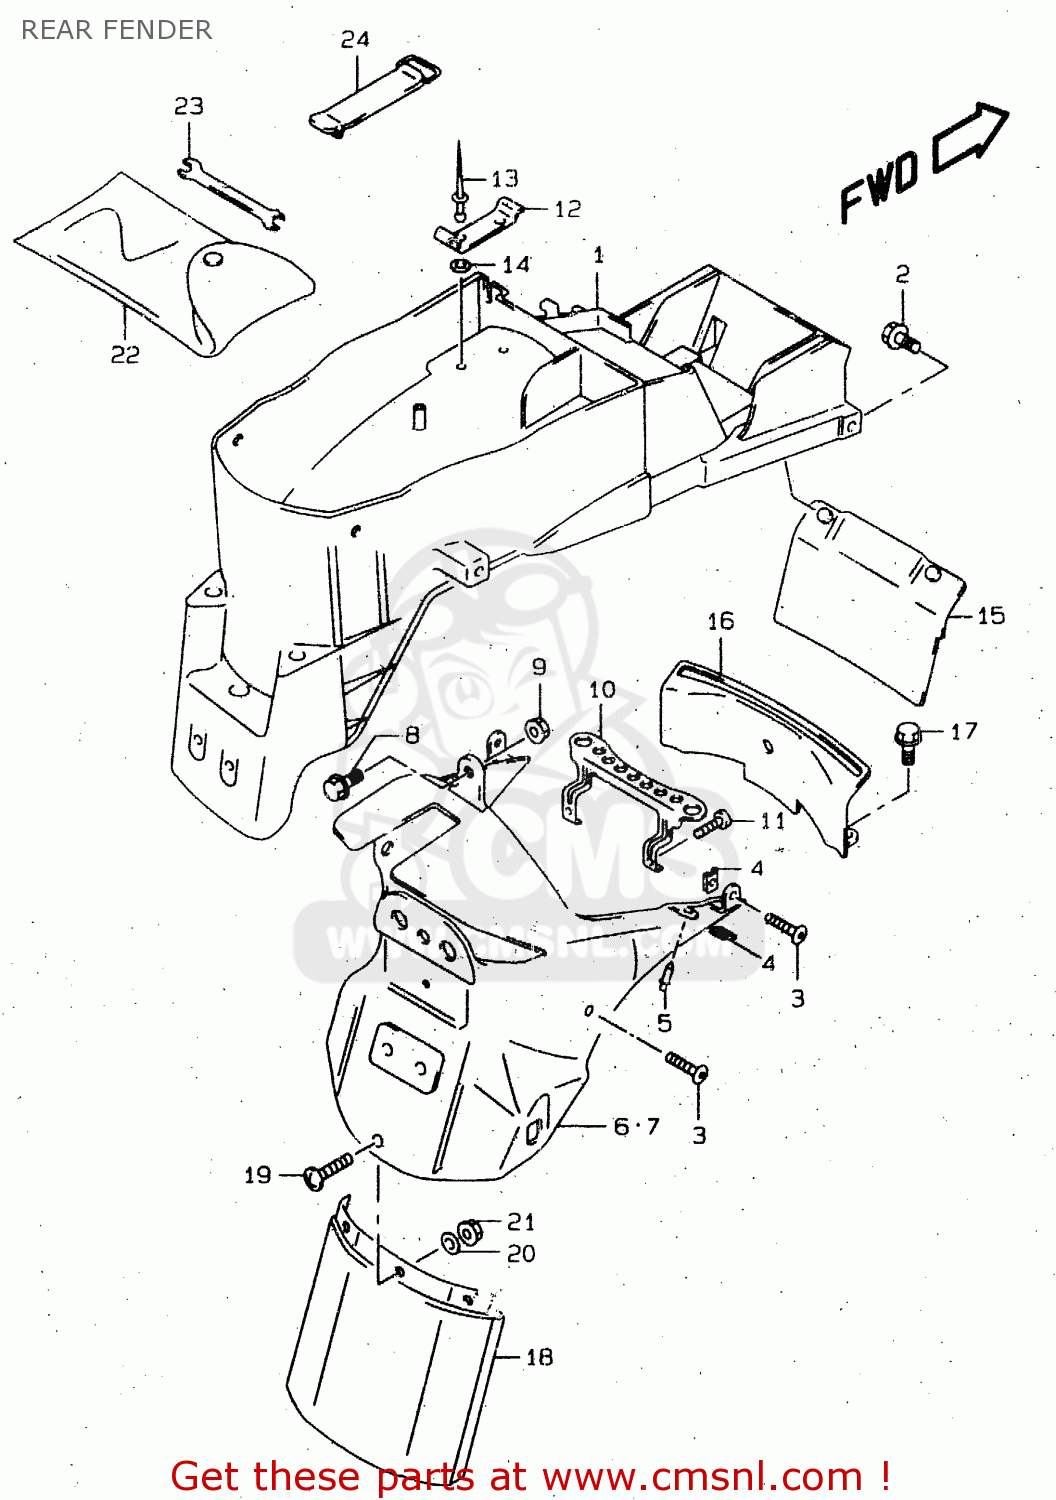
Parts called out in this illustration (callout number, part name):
1	FENDER,REAR,FRONT
2	BOLT 6X16
3	SCREW(5X12)
4	NUT
5	CLIP
6	FENDER,RR RR
7	FENDER,RR RR
8	BOLT(6X16)
9	NUT
10	BRACKET,REAR COMBINATION LAMP
11	SCREW(5X16)
12	HOLDER,TOOL
13	RIVET
14	WASHER
15	MUD GUARD,REAR FENDER
16	MUDGUARD,RR FENDER FR LWR
17	BOLT(6X16)
18	EXTENSION,RR FENDER
19	SCREW
20	WASHER(6.5X18X1.6)
21	NUT 6MM
22	TOOL ASSY
23	OPEN SPANNER(8X10)
24	BAND,TOOL
